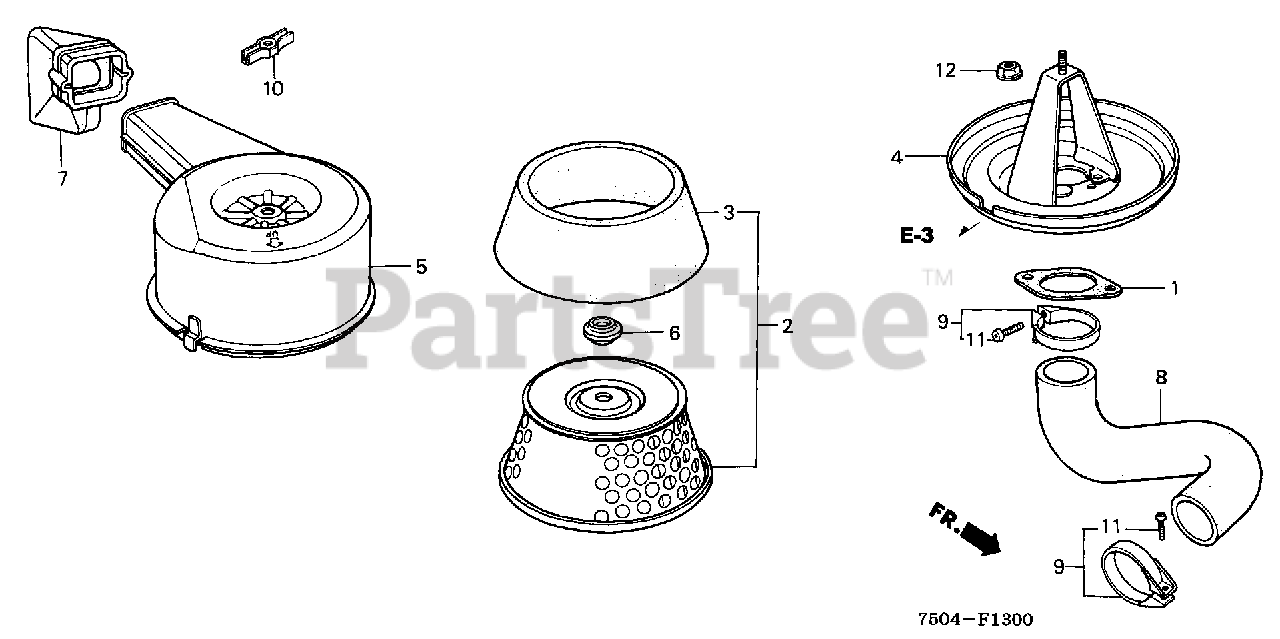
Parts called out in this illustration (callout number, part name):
1	GASKET, AIR CLEANER (NOT AVAILABLE)
2	ELEMENT, AIR CLEANER
3	FILTER (OUTER)
4	HOUSING, AIR CLEANER
5	COVER, AIR CLEANER
6	GROMMET, AIR CLEANER
7	TUBE, AIR CLEANER IN.
8	TUBE, AIR CLEANER CONNECTING
9	BAND, CONNECTING TUBE
10	WINGNUT, AIR CLEANER COVER
11	SCREW, PAN (4X26)
12	NUT, FLANGE (6MM)
